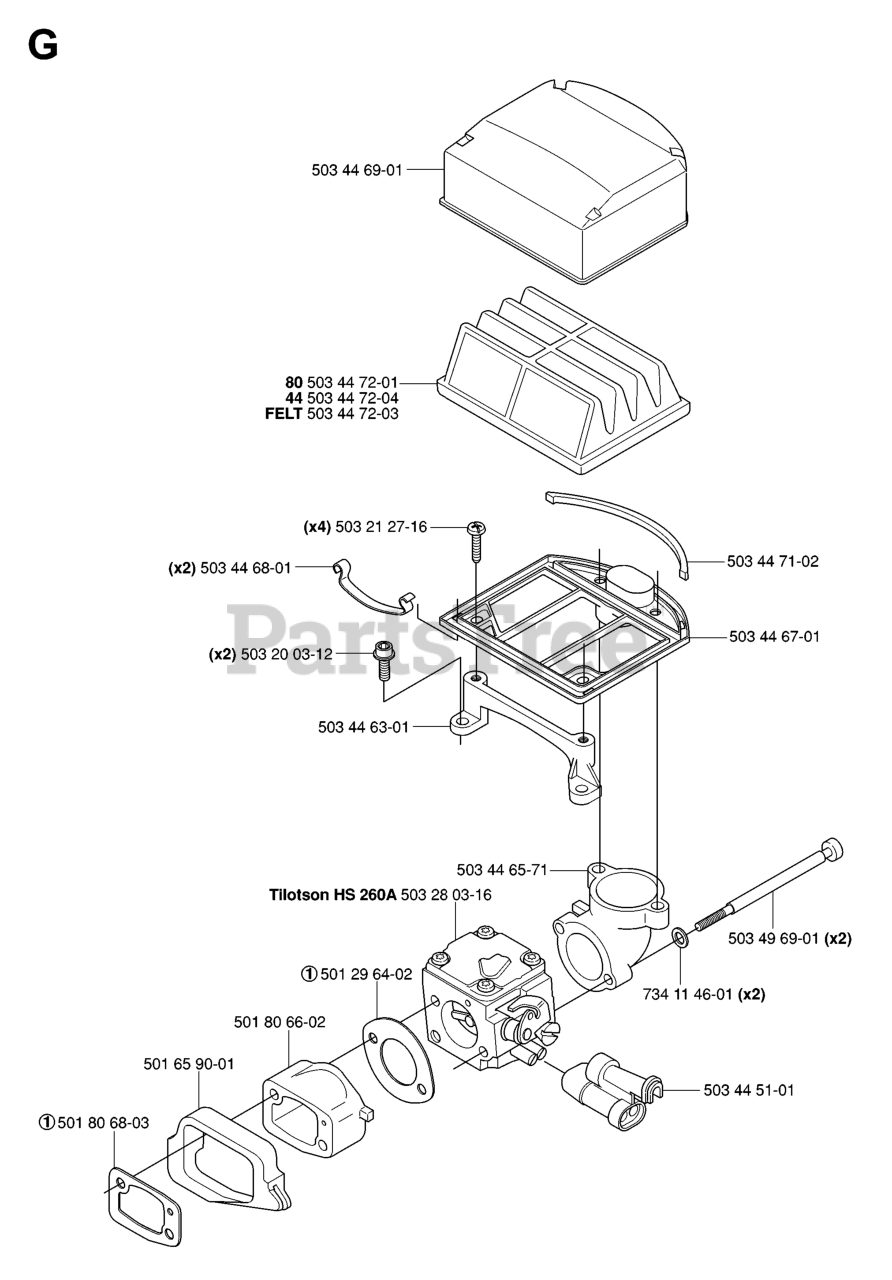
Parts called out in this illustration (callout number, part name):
1	ENGINE PULLEY
2	SCREW, 1/4-20 X 3/8, SET
3	HCS 3/8-24 X 2, GR8
4	BLADE DRIVER SPACER
5	BLADE, 21"
6	CLUTCH, WASHER
7	SLW 3/8 STD
8	BLADE ADAPTER
9	KEY, STEPPED
10	OIL W/LABEL, QT
11	DECK GUARD, BBC
12	SCREW #10-24 X 5/8
13	NUT 10-24 NYLOC
14	BOLT 3/8-16 X 1 1/2, ZINC YELL
15	BRACKET-SHAFT SUPT
16	BEARING - SHAFT SUPPORT
17	HEX CAP SCREW 1/4
